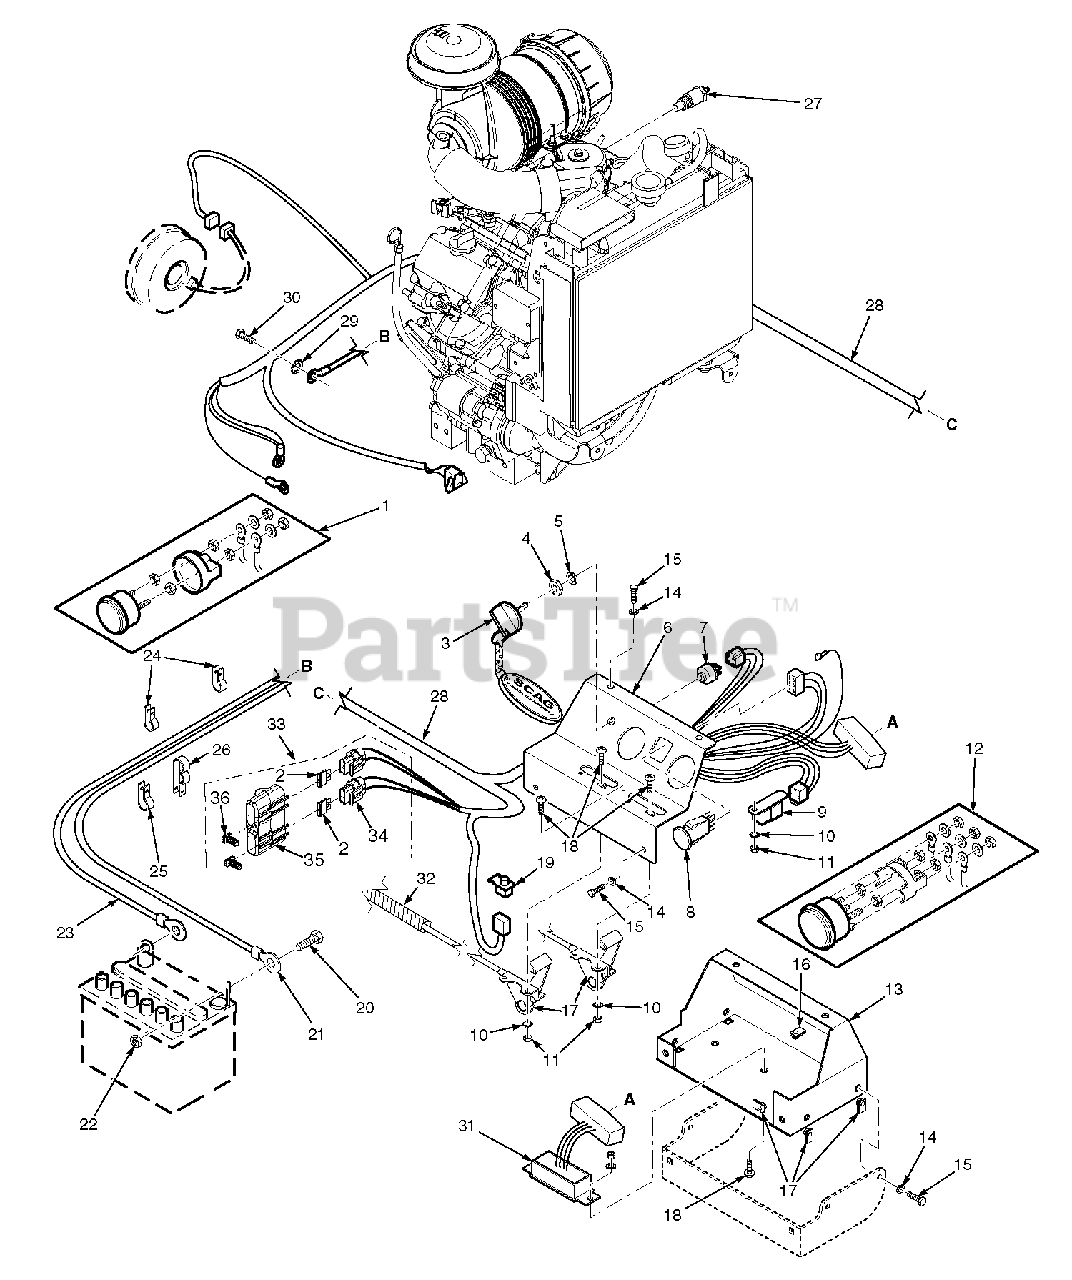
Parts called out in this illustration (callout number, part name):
1	Ammeter
2	Fuse, 20 AMP
3	Key, Ignition
3	Key Assembly w/Fob
4	Nut, Hex 5/8-32
5	Lockwasher, 5/8" Internal
6	Instrument Panel, Top w/Decals
7	Key Switch
8	Switch, PTO
9	Relay
10	Lockwasher, #10 External Tooth
11	Nut, Hex #10-32
12	Water Temp. Gauge
13	Base, Instrument Panel
14	Lockwasher, 1/4"
15	Bolt, Hex Head 1/4-20 x 3/4"
16	U-Nut, 1/4-20
17	Throttle And Choke Controls
18	Screw, Phillips Washer Head #10-32 x 1/2"
19	Switch, Interlock-Seat
20	Bolt, Hex Head 1/4-20 x 1/2"
21	Cable, Battery - Red
22	Nut, Hex 1/4-20
23	Cable, Battery - Black
24	Clamp, Cable 1/2" ID.
25	Clamp, Cable 3/4" ID.
26	Clamp, Cable
27	Sending Unit, Water Temp.
28	Wire Harness, STT Kawasaki Liquid-Cooled
29	Lockwasher, 5/16" External Tooth
30	Bolt, Hex Head M8-1.25 x 20mm
31	Electronic Module
32	Heatshield, Flexible
33	Double Fuse Assembly, Sealed
34	Fuse Holder
35	Cover, Sealed Double
36	Clip, Wire
